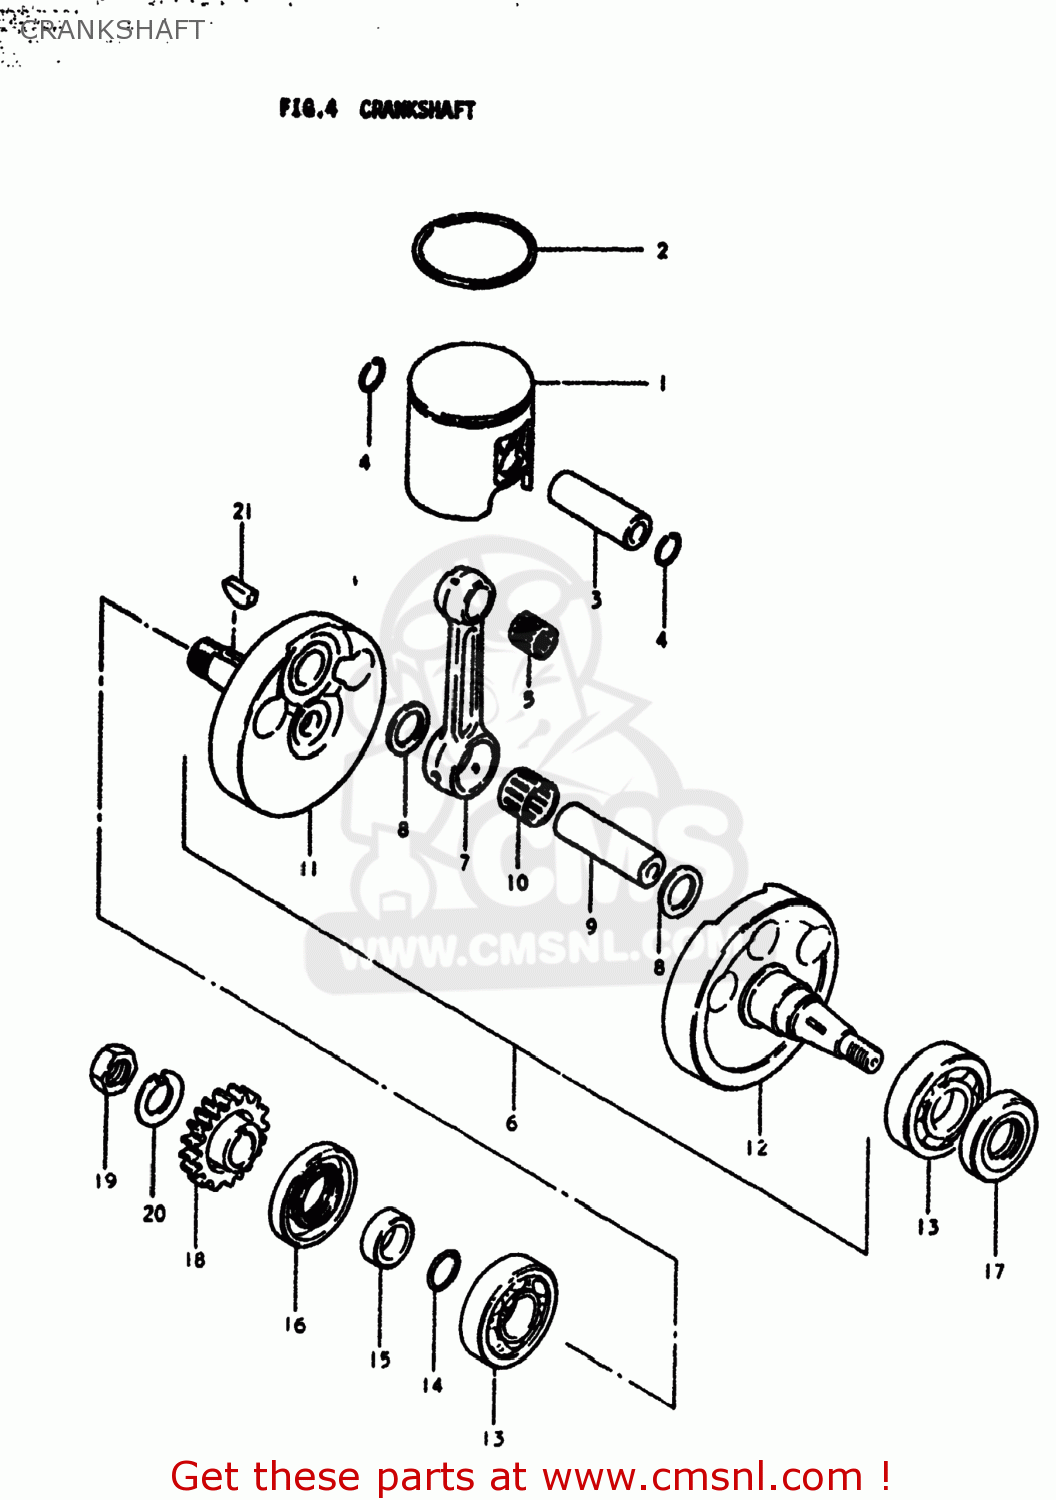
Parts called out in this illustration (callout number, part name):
1	PISTON
2	RING,PISTON
3	PIN,PISTON (18MM)
4	CIRCLIP
5	BEARING(18X23X22)
6	CRANKSHAFT ASSEMBLY
7	ROD,CONNECTING
8	WASHER(24X29X2)
9	PIN,CRANK
10	ROLLER BEARING (24X30X1
11	CRANKSHAFT
12	CRANKSHAFT,LEFT
13	BEARING
14	O RING(D:2.4,ID:19.8)
15	SPACER
16	SEAL,OIL(32X52X8.4)
17	SEAL,OIL(24X50X9)
18	GEAR,PRIMARY DRIVE
19	NUT
20	WASHER
21	KEY
